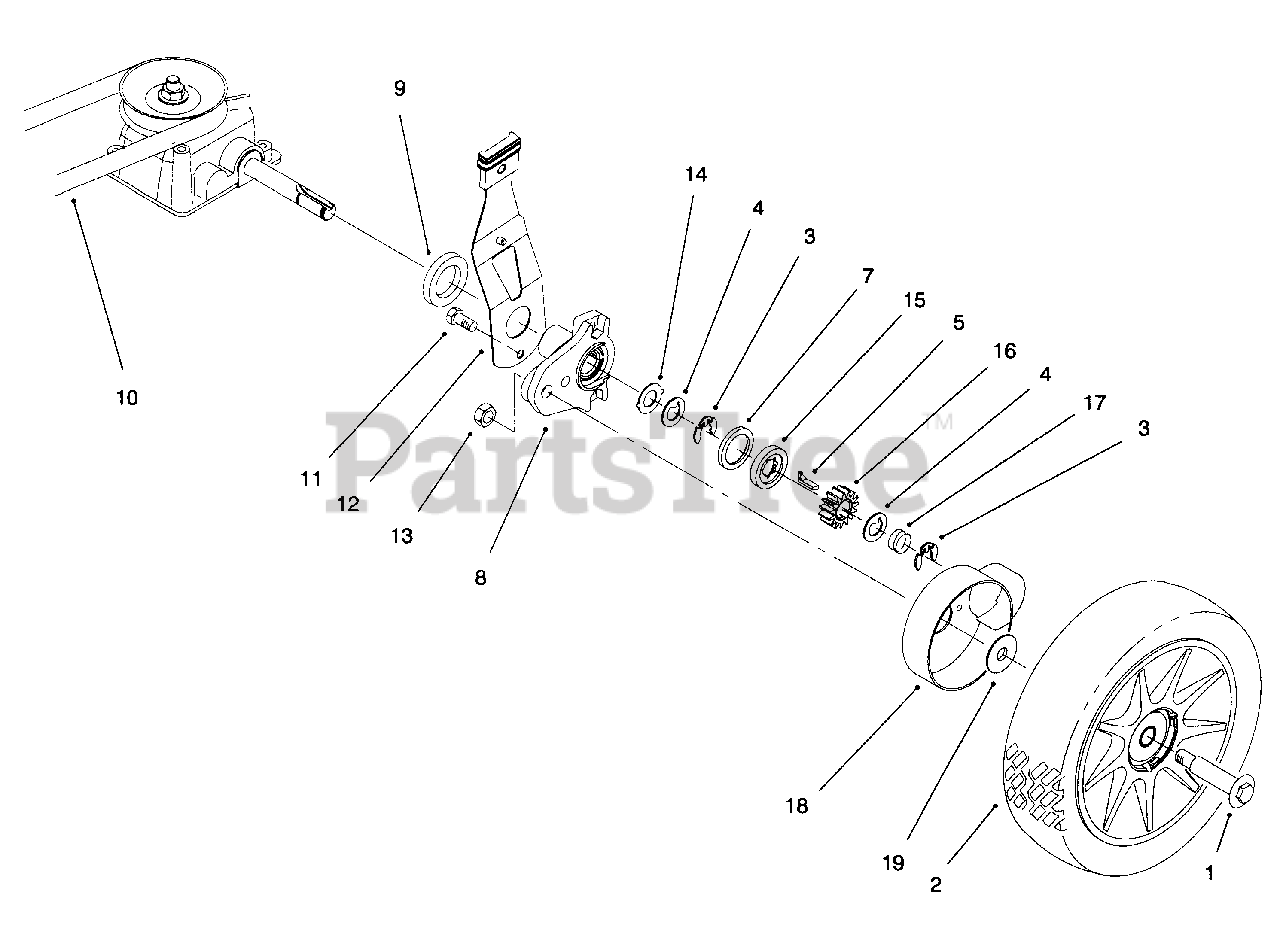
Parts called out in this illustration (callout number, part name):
1	Bolt-Shoulder
2	Wheel & Tire Assembly 8"
3	Ring-Retaining
4	Washer-Thrust Keyed
5	Key-Rocking L.H.
7	Ring-Friction
8	Arm-Height Adj. Rear
9	Spacer-Axle Shaft
11	Screw-Hex Hd.
12	Spring Arm Assembly
13	Nut-Lock
14	Washer-Thrust
16	Gear-Pinion
17	Spring-Compression
18	Cover-Wheel
19	Washer-Stepped
